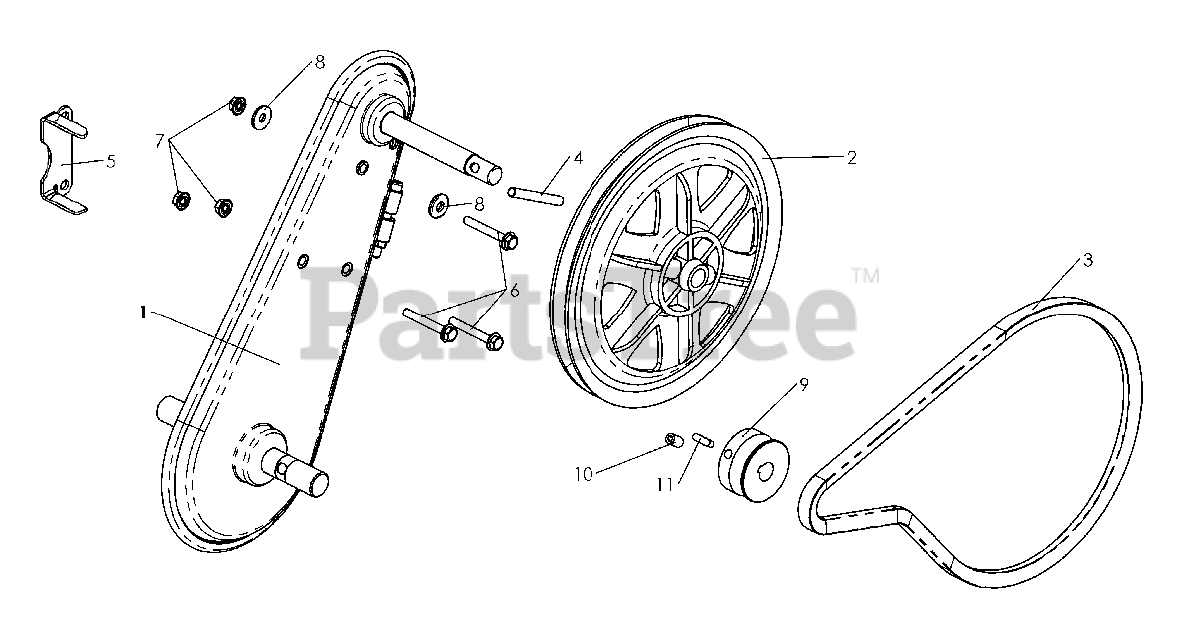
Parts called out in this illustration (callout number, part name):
7	NUT
8	WASHER
10	SCREW
